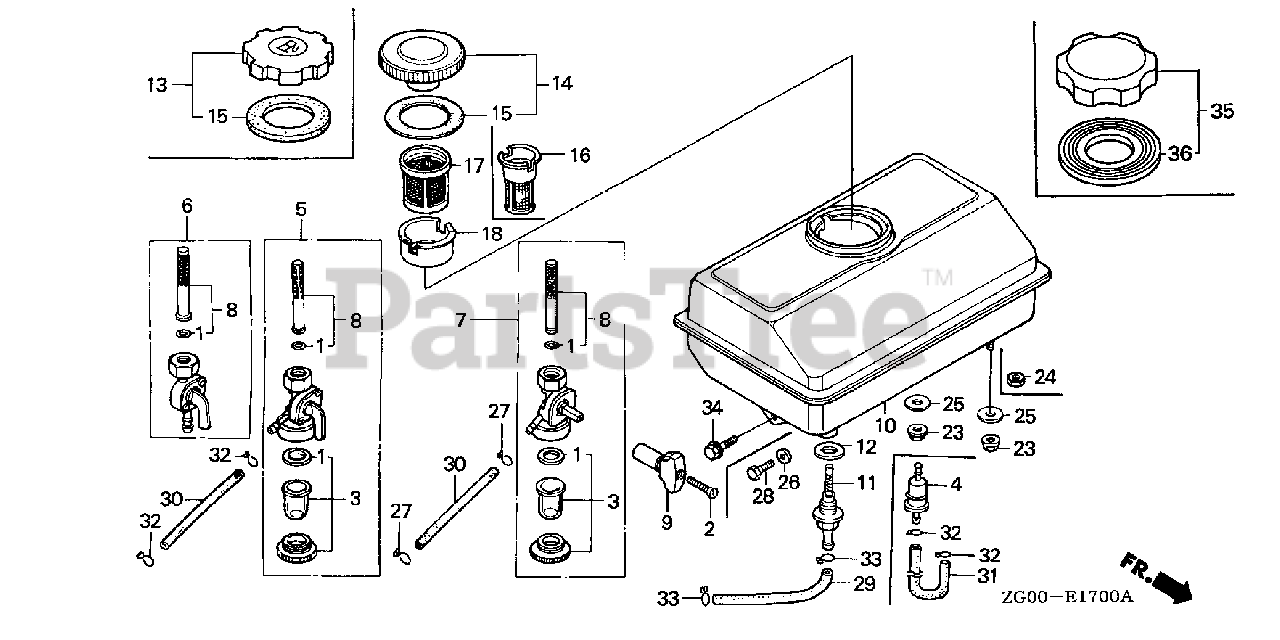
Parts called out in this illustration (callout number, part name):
1	GASKET SET, VALVE
3	CUP SET, FUEL STRAINER
5	PETCOCK ASSY.
8	SCREEN SET
10	TANK, FUEL
14	CAP, FUEL FILLER
15	GASKET, FUEL FILLER CAP
17	FILTER, FUEL
18	HOLDER, FUEL FILTER
23	NUT, FLANGE (6MM)
25	WASHER, SPECIAL (6MM)
30	BULK HOSE, FUEL (4.5X3000) (4.5X67)
33	CLIP, TUBE (B8)
34	BOLT, FLANGE (6X14)
